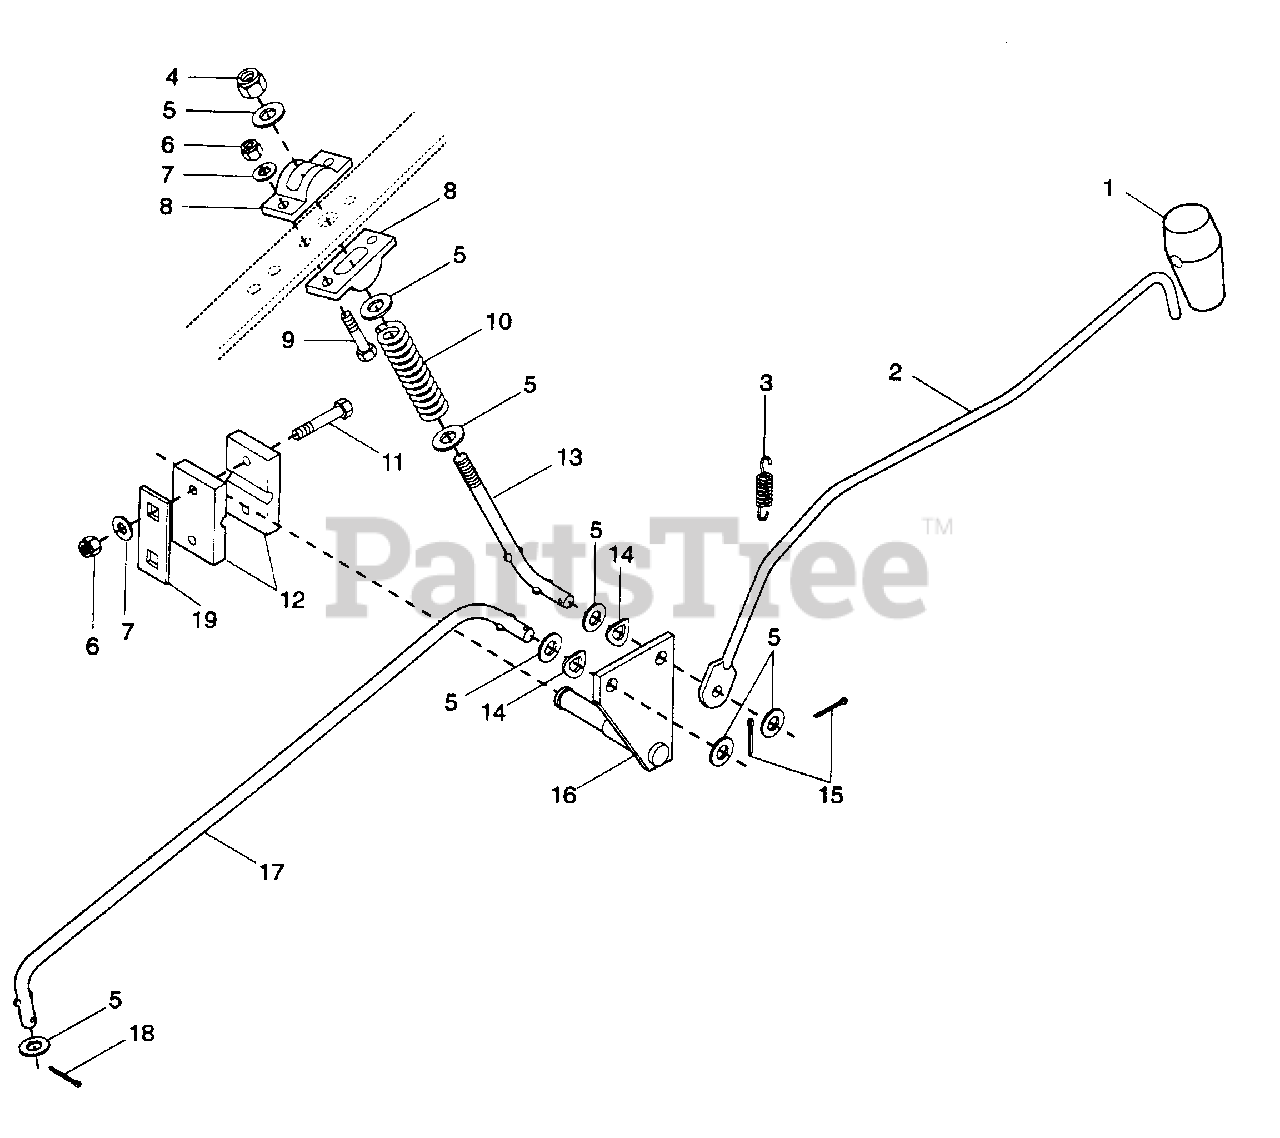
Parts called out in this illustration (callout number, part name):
1	HNDL, RUBBER SHIFTER
2	ROD, SHIFTER
3	SG-TENS .041 X 1.25 X .50 PL
4	NUT-LK-NYL .375-16 PL
5	WSHR-FL-STL .406 X .812 X .065 PL
6	NUT-LK-NYL .250-20 PL
7	WSHR-FL-STL .281 X .62 X .065 PL
8	CAM, SHIFTER
9	BLT-HEX .25-20 X 1.00 PL GR 5
10	SG-COMP .081 X .720 X 2.75 PL
11	BLT-HEX .25-20 X 1.50 PL GR 5
12	BLOCK, SHIFT LEVER
13	LINK, SHIFTER STOP
14	SPRING WASHER
15	PIN-COTR .12 X .75 PL
16	WLDMT, PTO BELLCRANK
17	LINK, PTO CONTROL
18	PIN-COTR .09 X .75 PL
19	SHIM, MOWER HT. ADJ. BRT.
